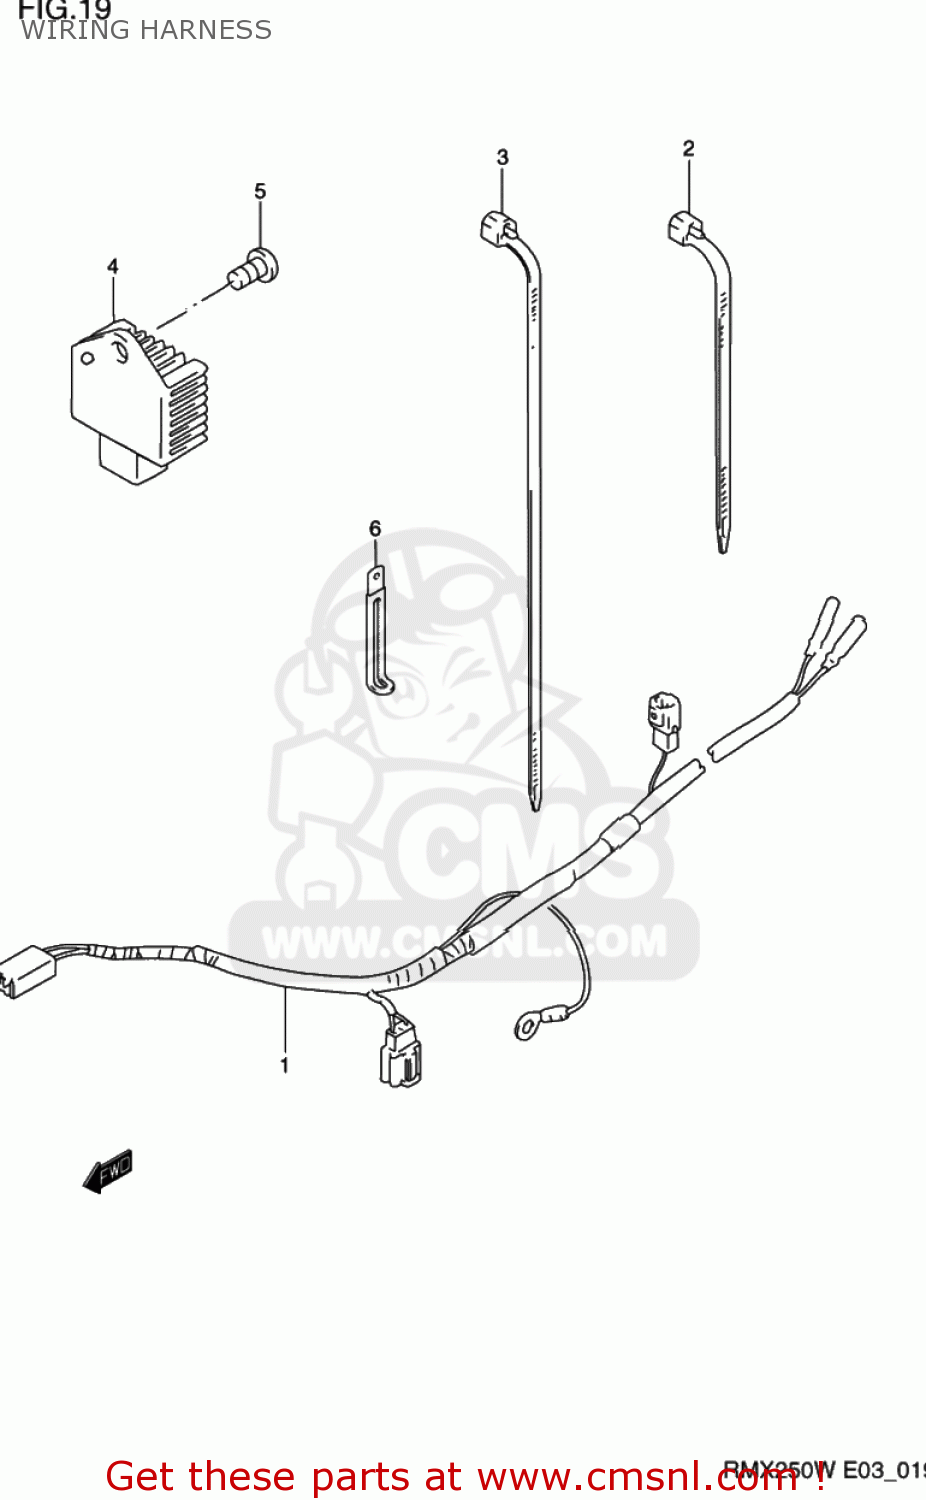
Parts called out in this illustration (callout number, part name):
1	HARNESS,WIRING
2	CLAMP(L:95)
3	CLAMP(L:235)
4	REGULATOR ASSY
5	SCREW
6	CLAMP(L:65)
